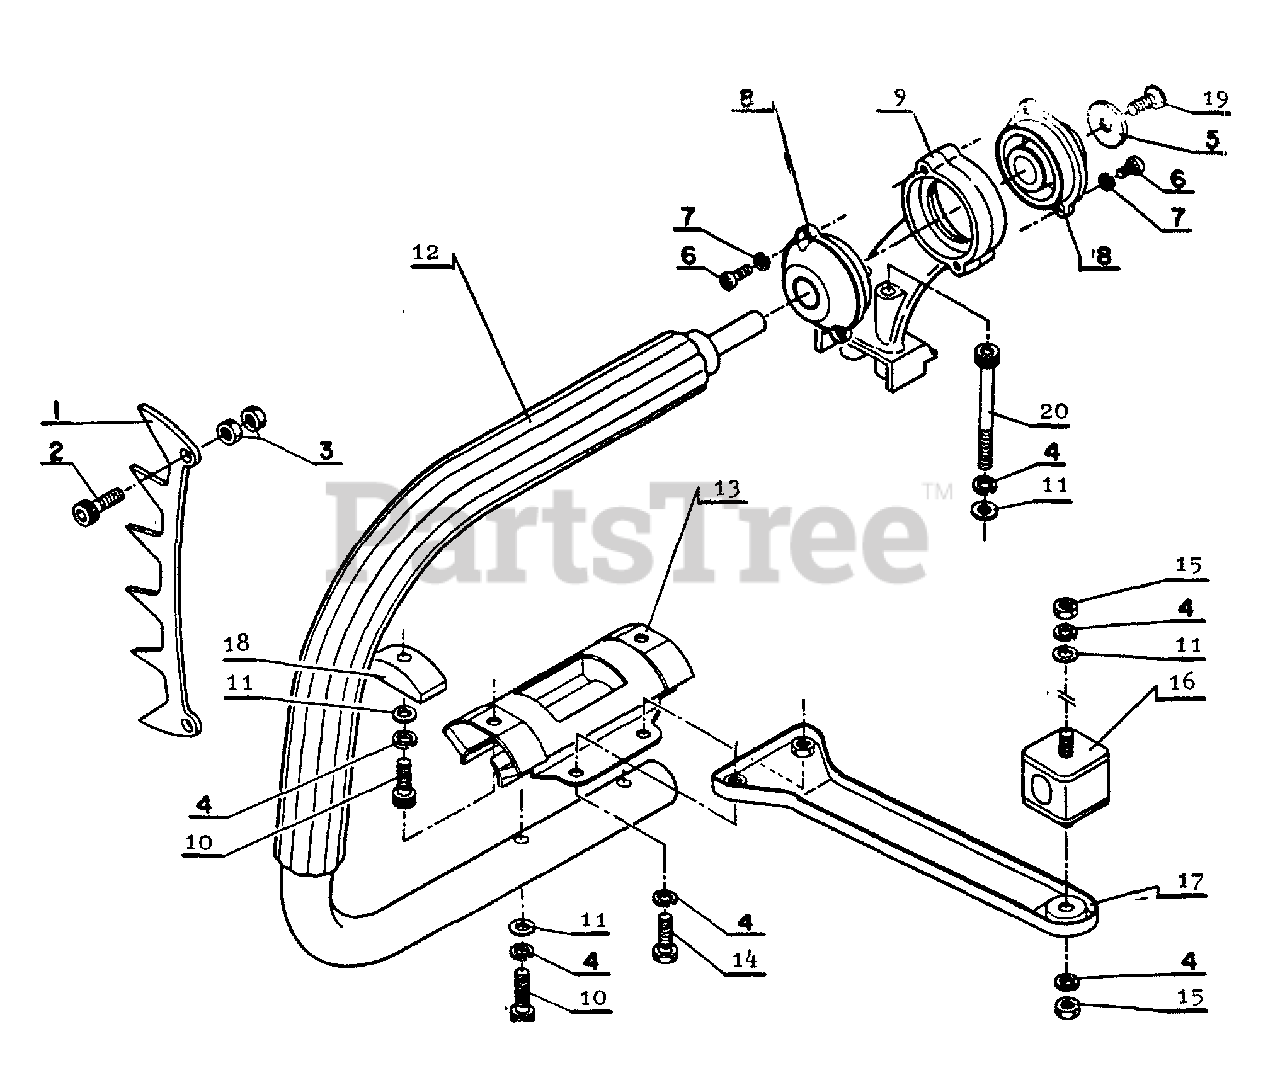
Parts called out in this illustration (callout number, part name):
1	BUMPER, SPIKED
2	SCREW - 5×15
3	NUT M5
4	WASHER, SPRING 5
5	WASHER
6	SCREW 3×8
7	LOCKWASHER - 3
8	CUSHION RUBBER (L-U)
9	BRACKET, HANDLE - UPPER
10	BOLT 5×20
11	WASHER
12	HANDLE, FRONT
13	CUSHION RUBBER (L-L)
14	BOLT - 5×8
15	LOCKNUT - 5
16	CUSHION RUBBER (L-L2)
17	BRACKET, HANDLE - LOWER
18	ADAPTER, CUSHION
19	SCREW - 5×12
20	BOLT 5×55
